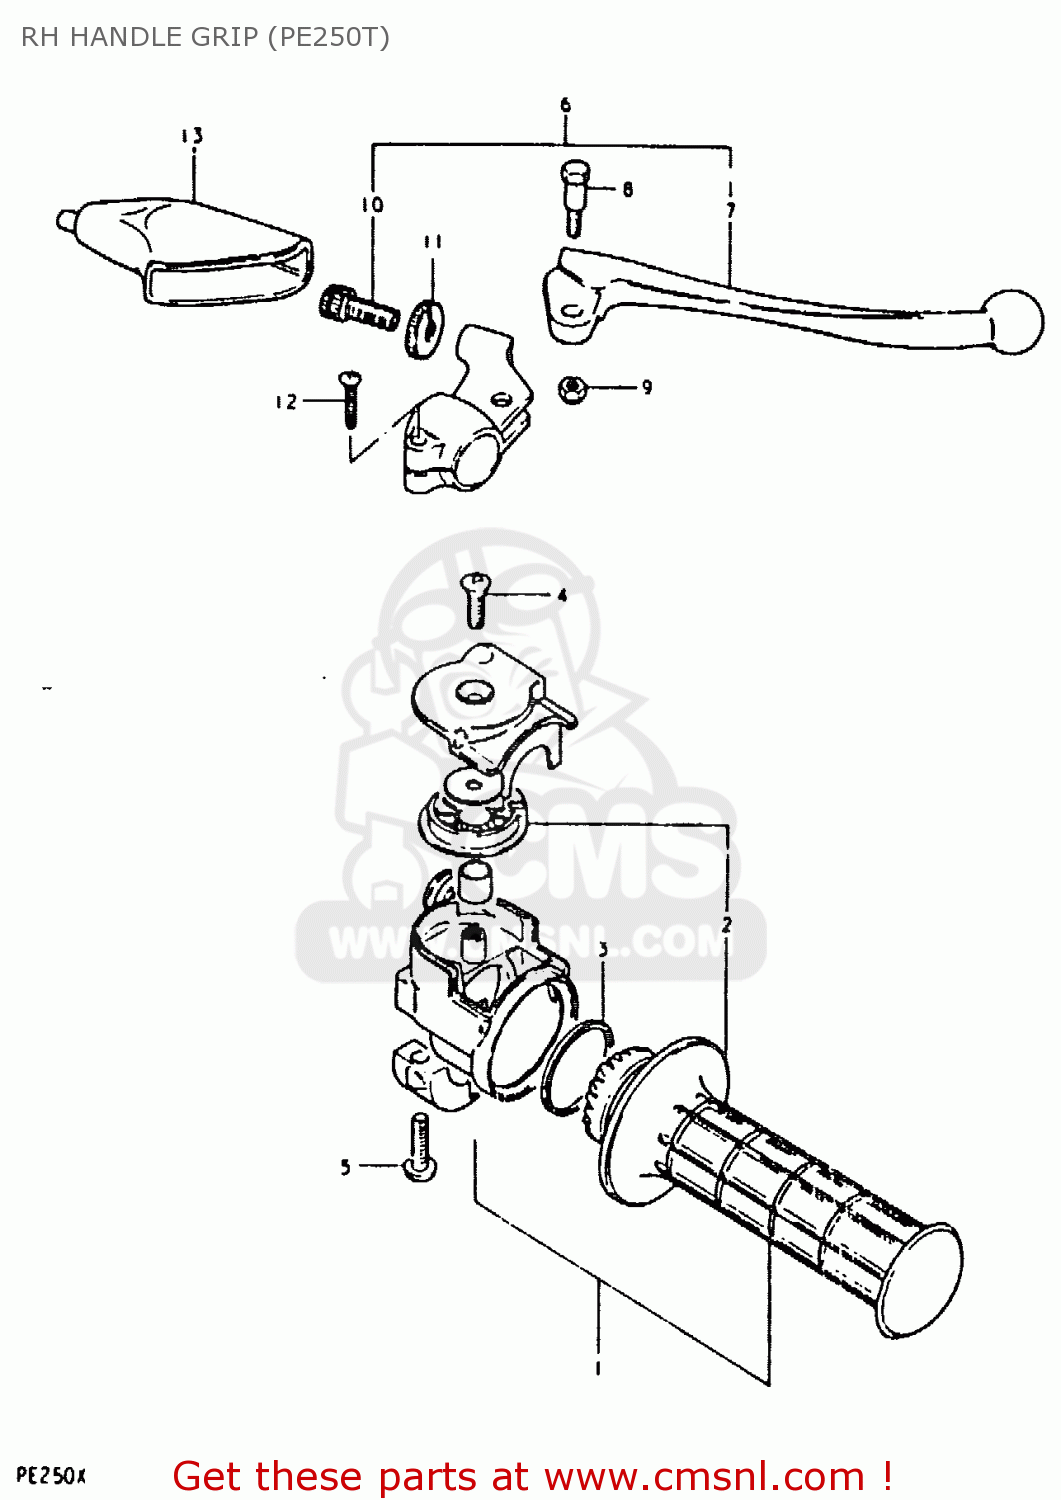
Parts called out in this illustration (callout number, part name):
1	CASE ASSEMBLY,THROTTLE
2	GRIP SET,THROTTLE
3	V-RING,THROTTLE GRIP
4	SCREW
5	SCREW 5X20
6	LEVER ASSY,BRAKE
7	LEVER,BRAKE
8	BOLT,LEVER
9	NUT 6MM
10	ADJUSTER,CABLE
11	NUT,CABLE ADJUSTER
12	SCREW
13	COVER,CLUTCH LEVER
